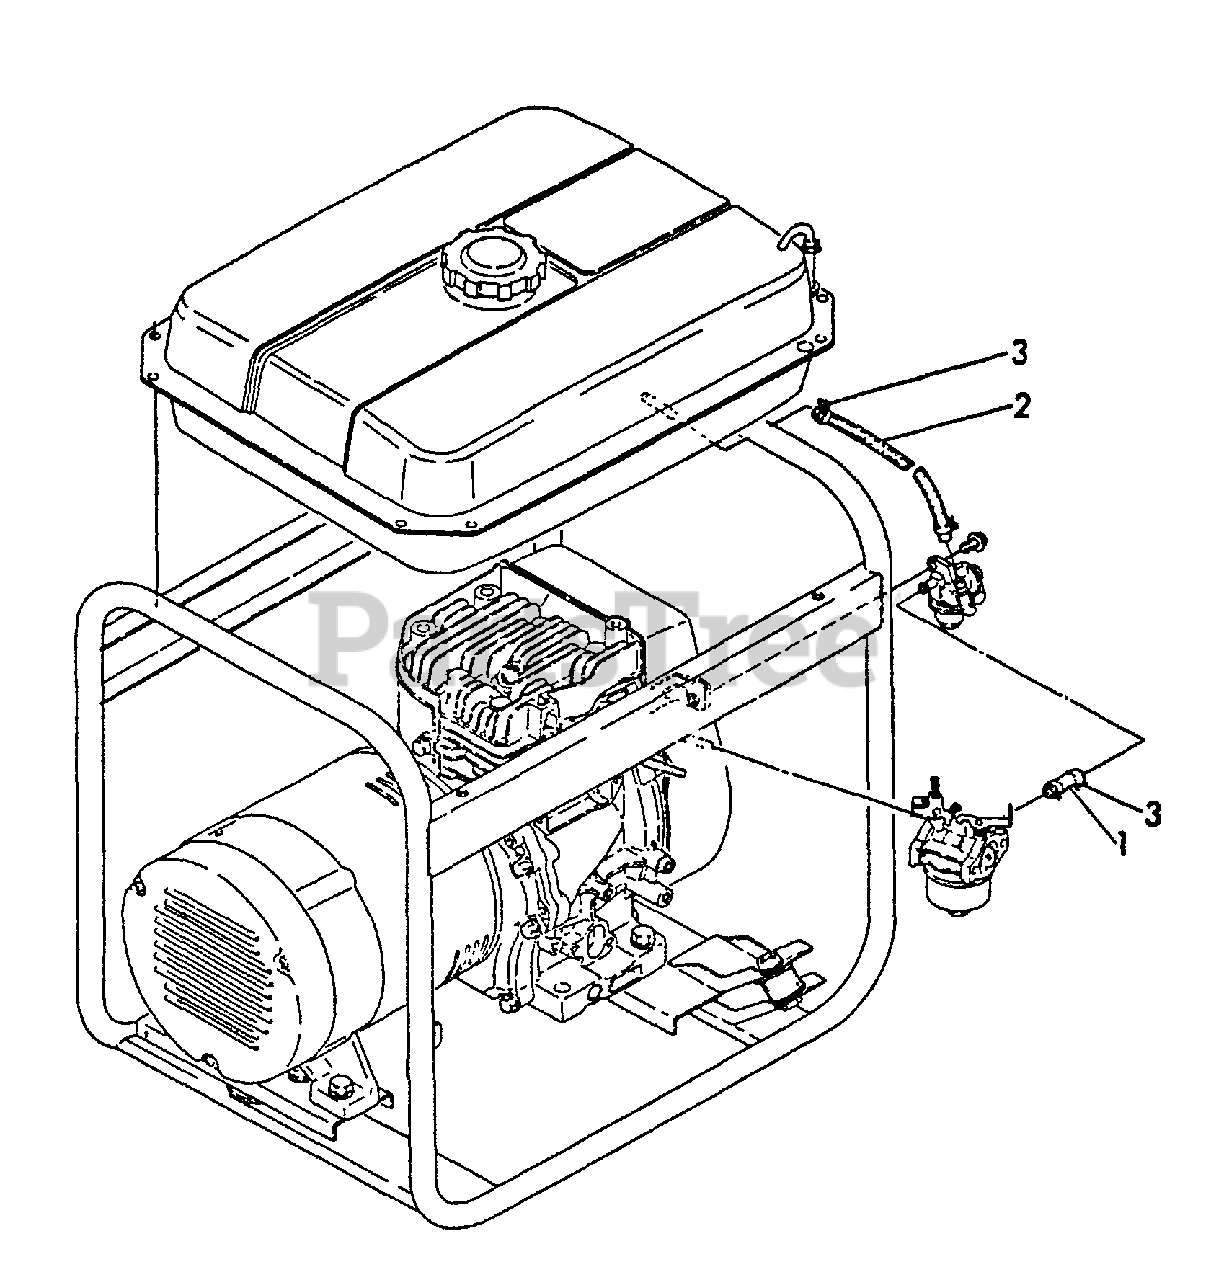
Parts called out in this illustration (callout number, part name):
1	PIPE - FUEL
2	PIPE - FUEL
3	CLAMP, HOSE - 10
